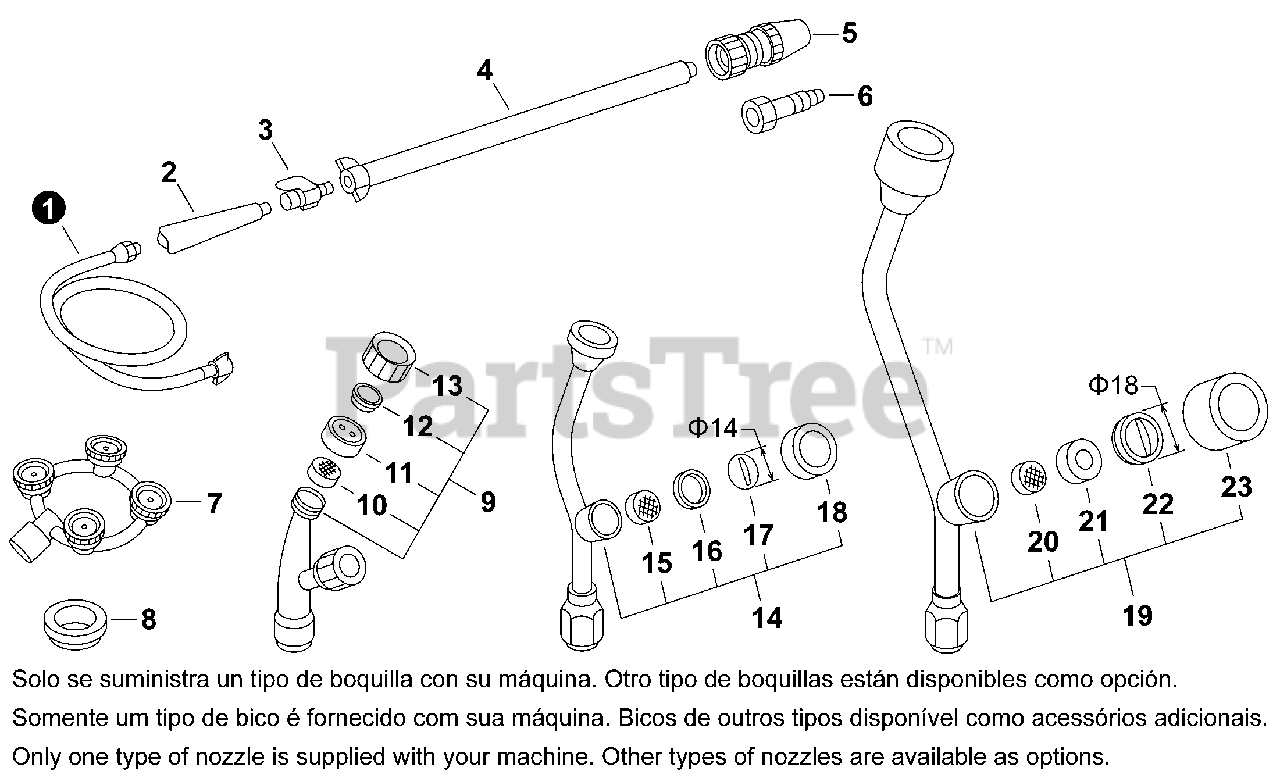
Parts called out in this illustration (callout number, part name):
1	HOSE ASSY, SPRAYER
2	GRIP, WAND
3	VALVE, NOZZLE
4	WAND, SPRAYER
5	NOZZLE #33
6	NOZZLE, ADJUSTABLE
7	NOZZLE, 4 HEAD RING
8	ADAPTOR, TEE-JET? NOZZLE
9	NOZZLE, 2 HEAD PLASTIC D-5
12	NOZZLE J-5 W/P
13	CAP, NOZZLE
14	NOZZLE, 2 HEAD METAL
17	NOZZLE J-5
18	CAP, NOZZLE
19	NOZZLE, 2 HEAD METAL
22	NOZZLE J-5 W/P
23	CAP, NOZZLE
